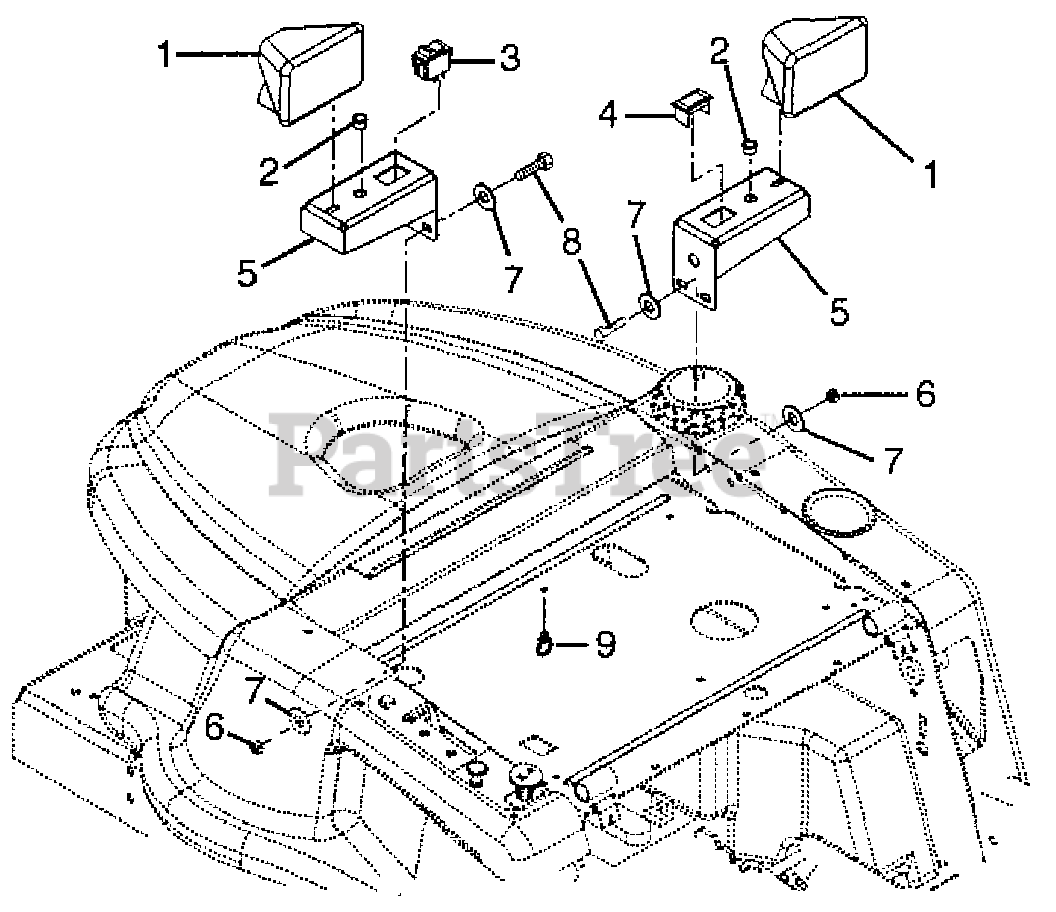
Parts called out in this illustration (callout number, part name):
1	Headlight
2	Snap Bushing
3	Light Switch
4	Switch Cover
5	Headlight Bracket
6	Nut-Locking-Nylon .312-18
7	Washer-Flat-Steel .344 x .688 x .065
8	Bolt-Hex .31-18 x 1.00 Grade 5
9	Tube Clip 3/4
